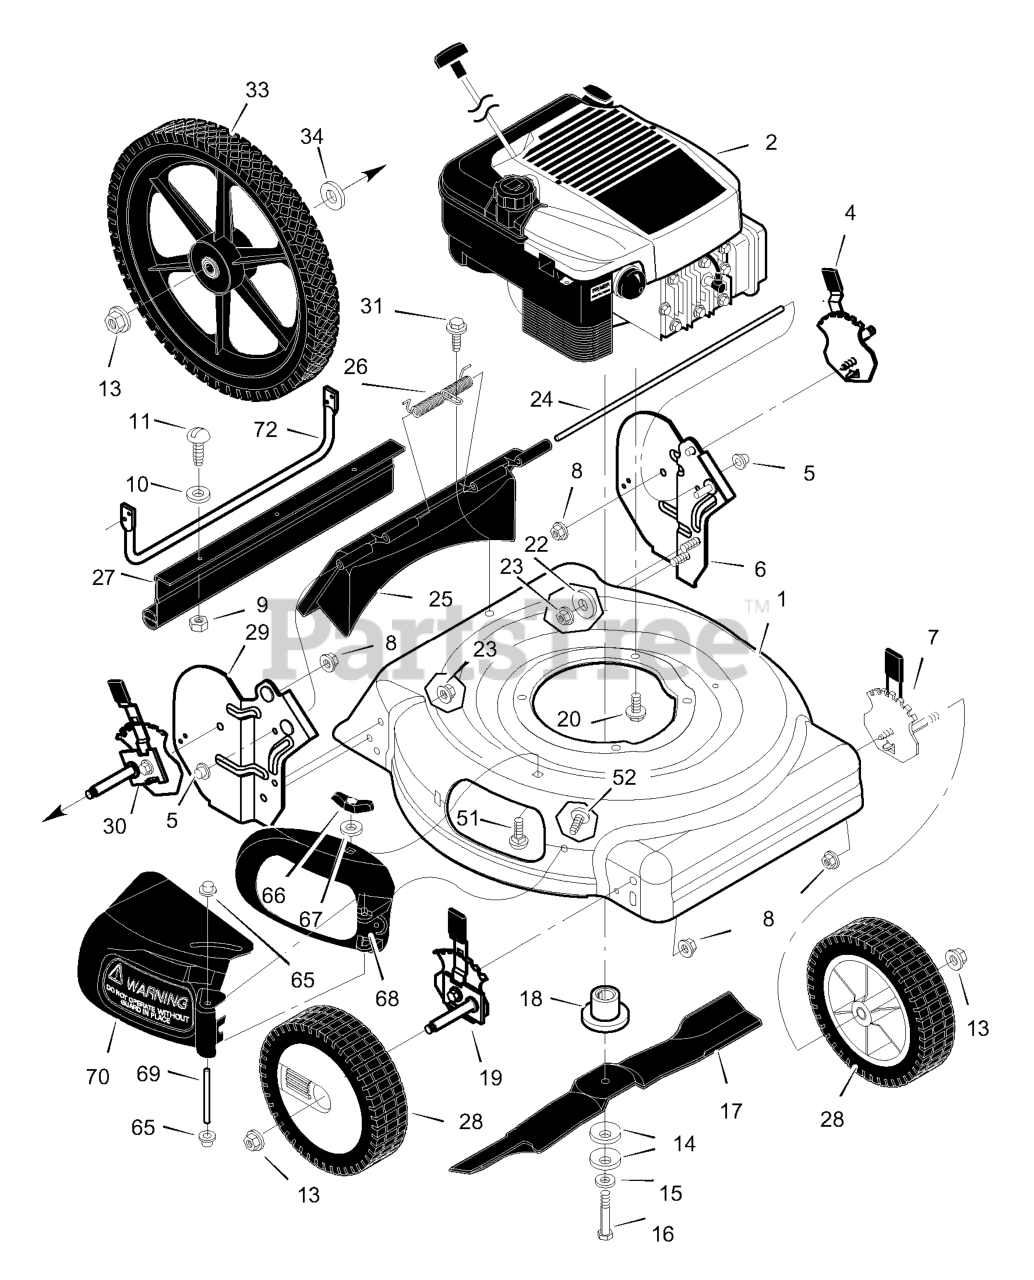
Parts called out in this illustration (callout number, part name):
1	Housing
2	Engine
4	Adjuster, Left Height
5	Push On Cap
6	Bracket, Left Handle
7	Adjuster, Left Frt. Height
8	Nut, Flange
9	Nut, Hex
13	Nut, Flange
14	Washer, Belleville
18	Adapter, Blade
19	Adjuster, Right Frt. Height
20	Bolt, Engine
22	Washer
23	Nut, Flange
24	Rod, Pivot
25	Door, Rear
27	Guard, Rear
28	Wheel
29	Bracket, Right Handle
30	Adjuster, Right Height
33	Wheel, Rear
34	Washer
51	Bolt, Carriage
65	Push On Cap
66	Wingnut
69	Pin, Pivot
70	Deflector, Chute
